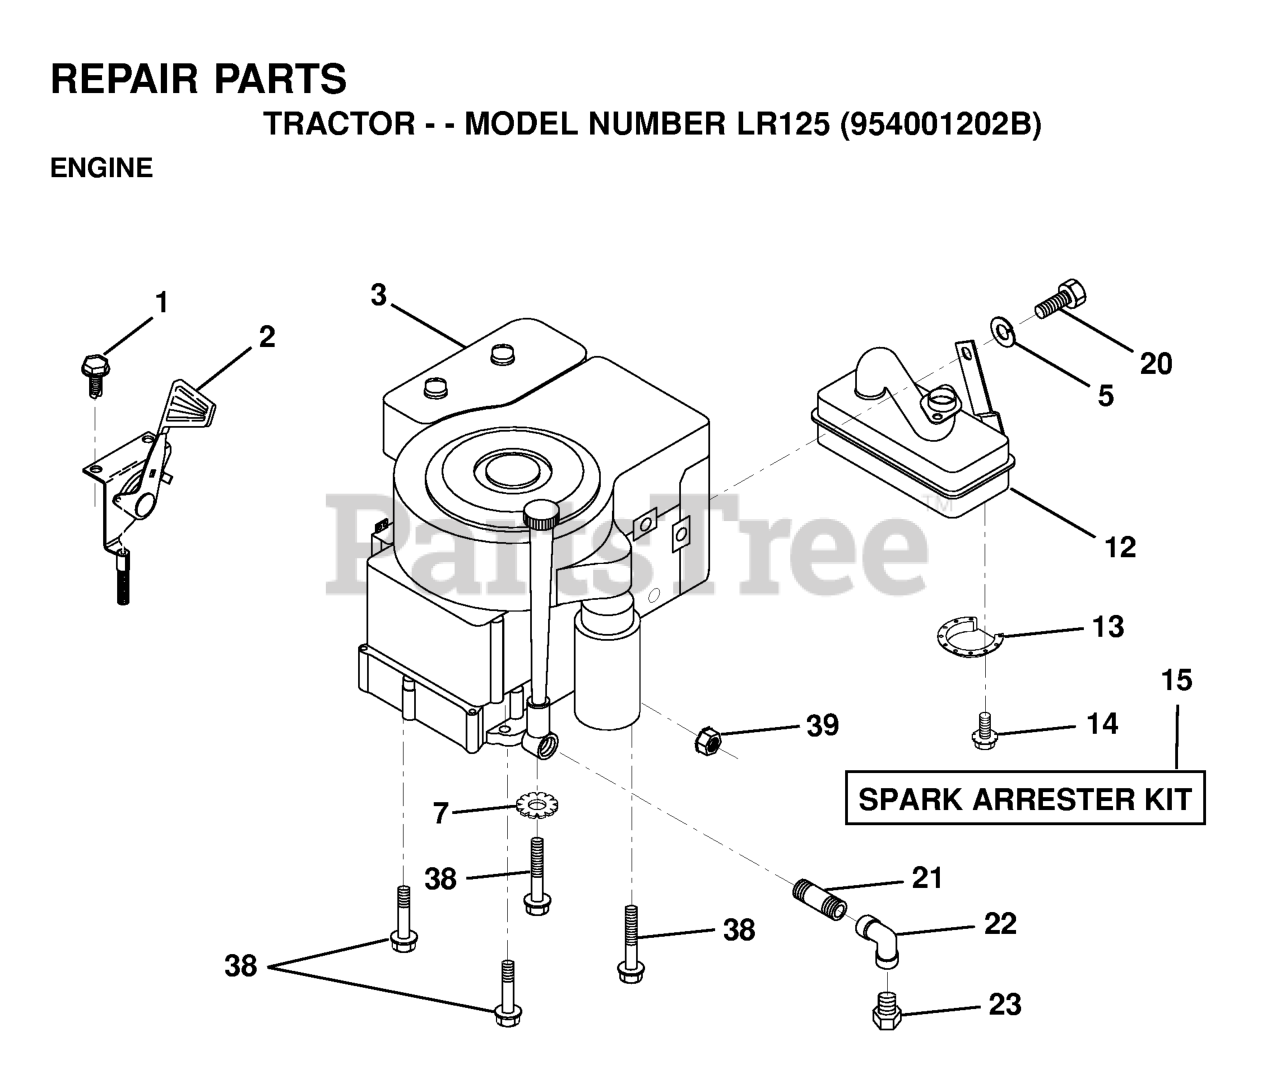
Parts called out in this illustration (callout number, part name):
2	THROTTLE CONTROL
5	WASHER.LOCK.HVY.HLCL.SPR.5/16
7	LOCKWASHER
12	MUFFLER KOH
13	DEFL MUFFLER LTV
14	SCREW
15	KIT.SPARK ARRESTOR 794945 B&S
20	Bolt, Hex Head, Fin. 5/16-18 x 1/2
21	Std. Pipe Nipple 3/8 - 18 NPT x 3 1/2
22	ELBOW
38	BOLT, HEX
39	NUT
